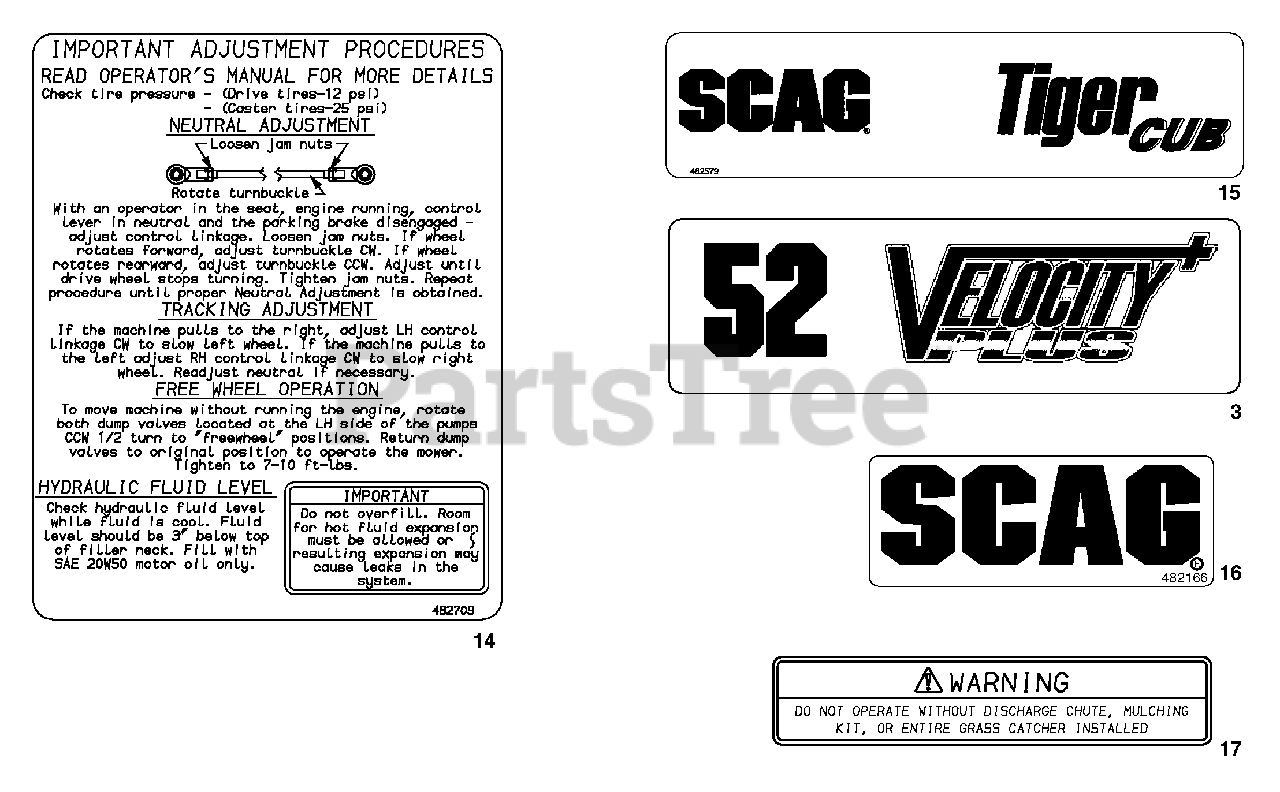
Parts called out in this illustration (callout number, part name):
3	Decal, 48V
14	Decal, Seat Support
15	Decal, Rear Bumper
16	Decal, Front Footplate
17	Decal, Discharge Chute
